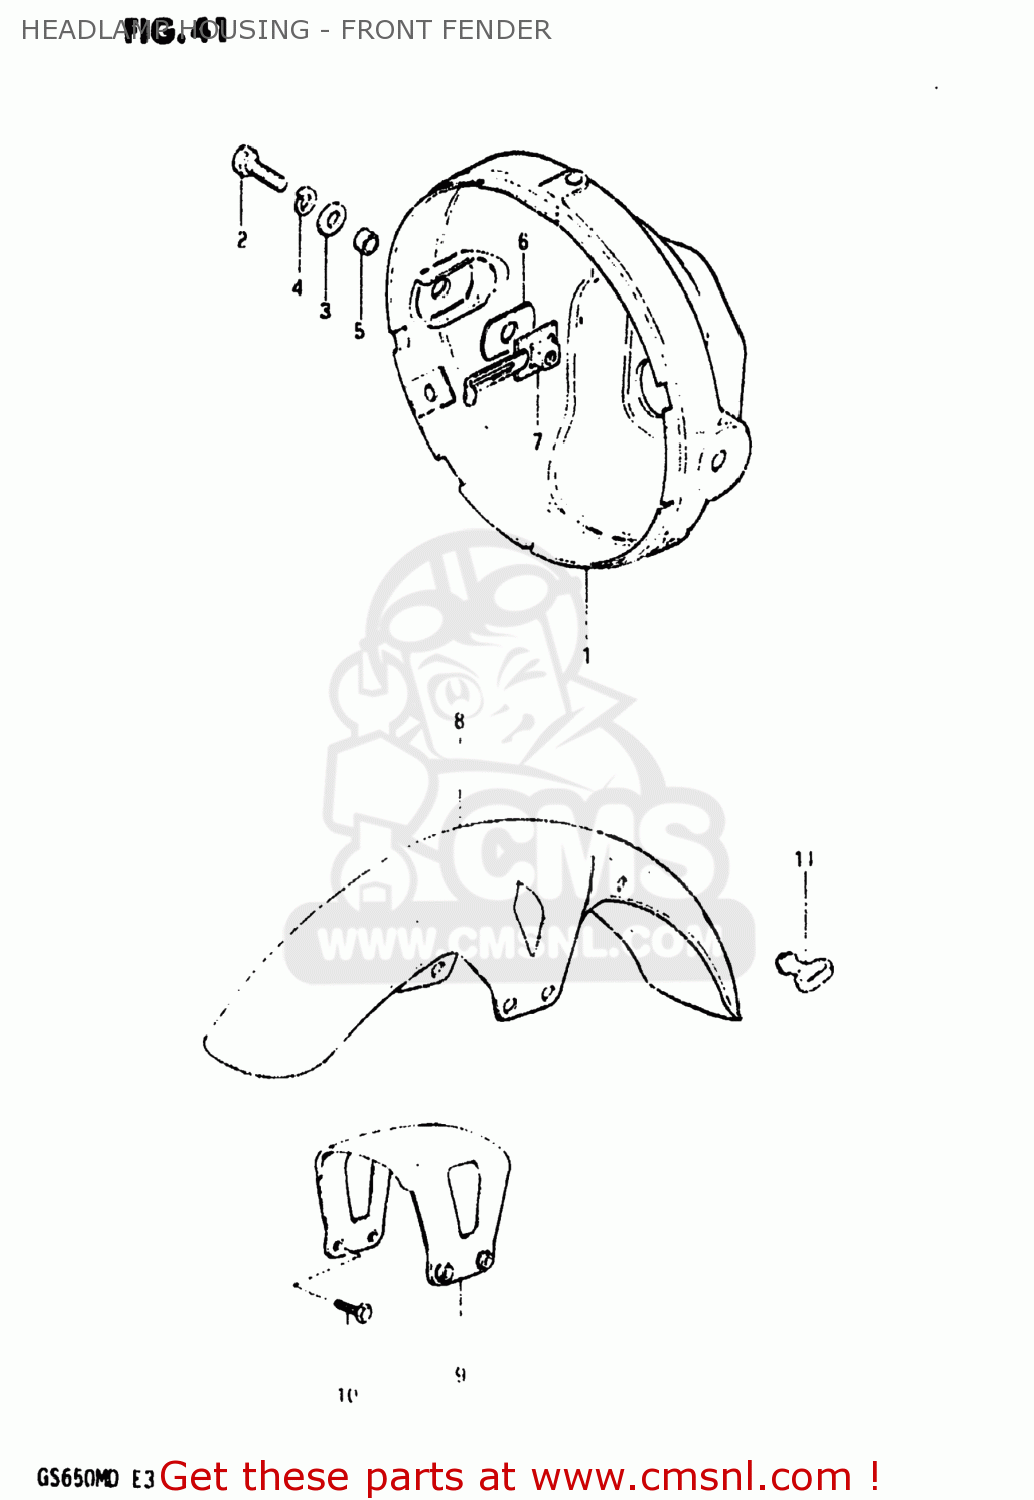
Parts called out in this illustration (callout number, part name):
1	HOUSING,HEADLAMP
2	BOLT
3	WASHER
4	LOCK WASHER
5	SPACER (8.8X12X7)
6	CUSHION
7	PLATE,HEADLAMP HOUSING
8	FENDER,FRONT
9	BRACE,FRONT FENDER
10	BOLT 8X16
11	GUIDE,CABLE
